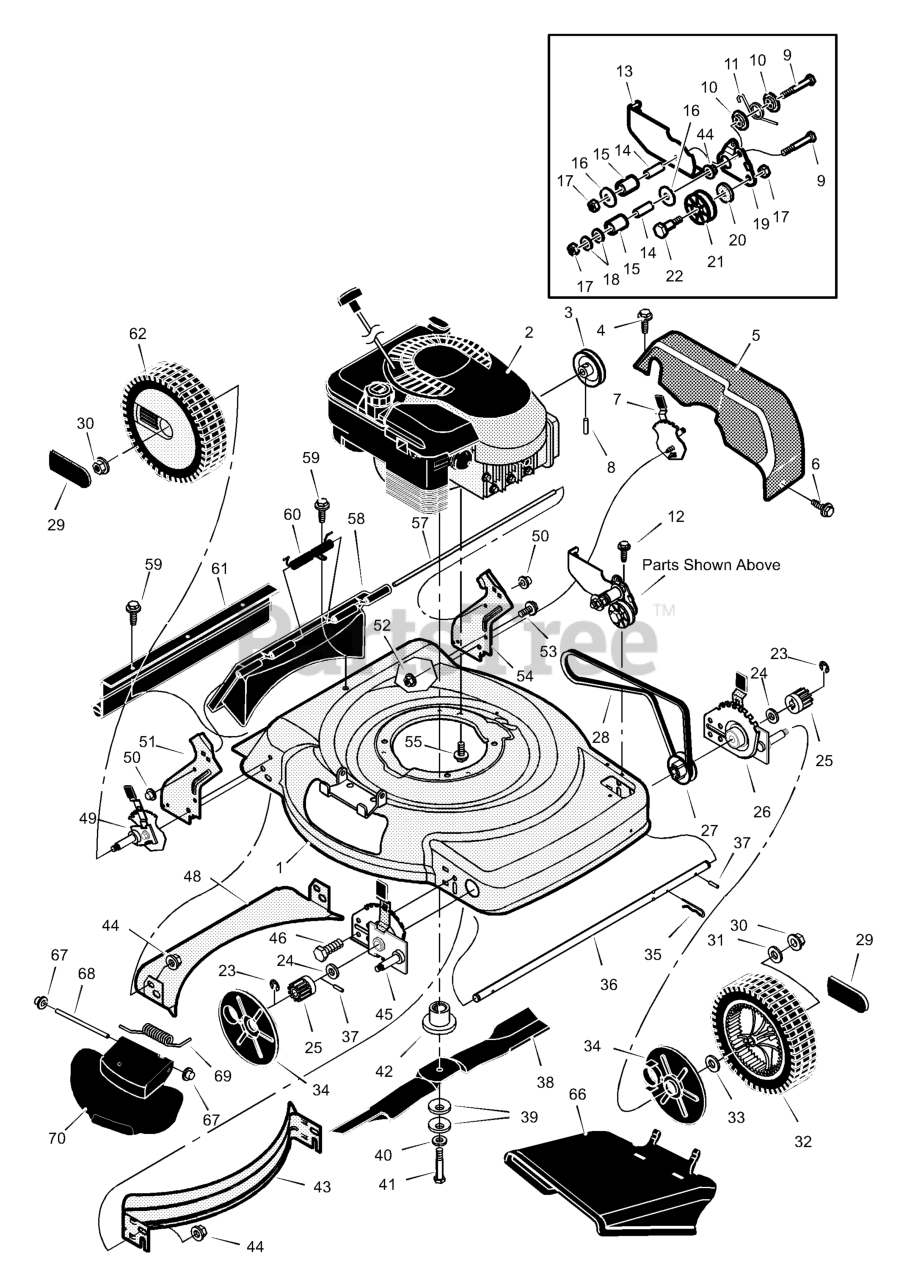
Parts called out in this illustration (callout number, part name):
1	Housing
2	Engine *
3	Pulley, Drive
5	Cover, Belt (Black)
7	Adjuster, Left Rear Height
8	Pin, Spring
10	Spacer, Idler Arm
12	Screw
13	Bracket, Idler Support
14	Bearing, Idler
15	Pulley, Idler
17	Nut
18	Washer
19	Arn, Pivot
20	Spacer, Idler
21	Pulley, Idler
22	Bolt, Shoulder
25	Gear, Pinion
26	Adjuster, Left Front Height
27	Pulley, Axle
29	Cap, Hub
30	Nut, Flange
31	Washer
32	Wheel & Tire, Front
34	Cover, Dust
35	Pin, Hair
37	Pin, Drive
39	Washer, Belleville
42	Adapter, Blade
43	Baffle, Front
44	Nut, Flange
45	Adjuster, Right Front Height
46	Bolt
48	Baffle, Rear
49	Adjuster, Right Rear Height
50	Push On Cap
51	Bracket, Right Handle
52	Nut, Flange
53	Bolt
54	Bracket, Left Handle
55	Bolt, Engine
57	Rod, Pivot
58	Door, Rear (Black)
60	Spring
61	Guard, Rear
62	Wheel & Tire, Rear
66	Deflector, Chute
67	Push On Cap
68	Rod, Pivot
69	Spring, Torsion
70	Cover, Mulch (Black)
